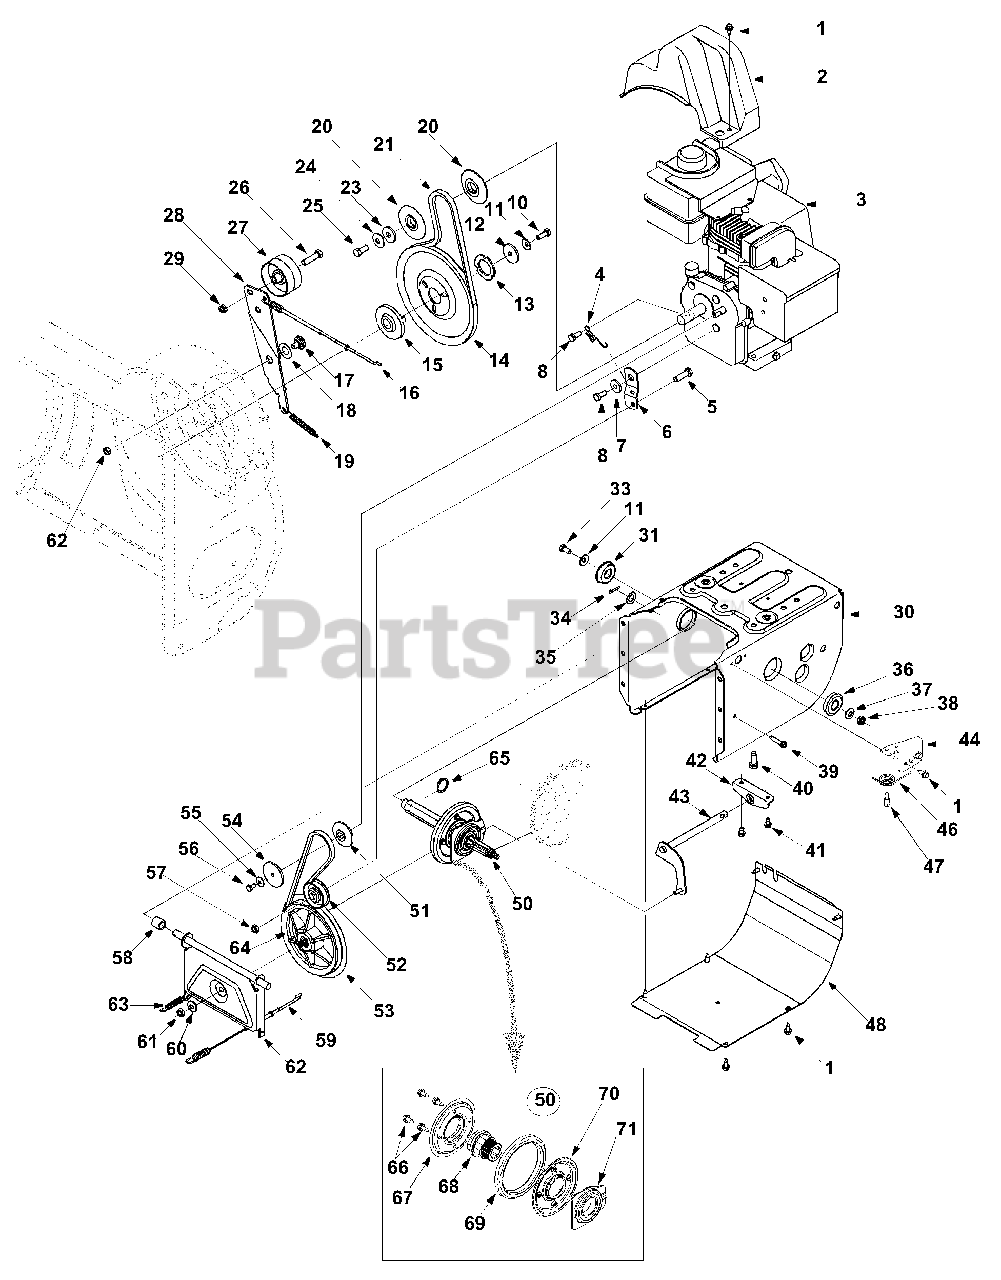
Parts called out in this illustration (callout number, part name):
1	TT Screw 1/4-20 x 0.625"
2	Belt Cover
4	Extension Spring
5	Hex Bolt 3/8-16 x 1.25"
8	Lock Bolt 5/16-24 x 0.75"
10	Lock Bolt 5/16-24 x 0.875"
11	Bell Washer
12	Flat Washer
13	Special Washer
14	Auger Pulley
15	Pulley Adapter
16	Auger Clutch Cable
17	Shoulder Screw
18	Flat Washer
19	Extension Spring
20	Pulley Half
21	V-Belt
23	Flat Washer
24	Bell Washer
25	Hex Bolt 3/8-24 x 0.875"
26	Hex Bolt (Special) 3/8-24 x 1.5"
27	Flat Idler
29	Jam Lock Nut
30	Snow Thrower Frame
31	Ball Bearing
33	Lock Bolt 5/16-18 x 0.625"
34	Cotter Pin
35	Flat Washer
36	Ball Bearing
37	Bell Washer
38	Jam Lock Nut 3/8-24
39	TT Screw 1/4-20 x 1.25"
40	Tt Sems Screw 3/8-16 x 1.0"
41	TT Screw 1/4-20 x 0.5"
43	Shift Rod Assembly
47	C Screw 1/4-28 x 0.375"
51	Pulley Half
52	Flat Idler Pulley
54	Pulley Half
55	Bell Washer
56	Hex Bolt 1/4-28 x 0.50"
57	Jam Nut 3/8-16
58	Spacer
59	Drive Cable
60	Bell Washer
61	Jam Nut
64	Friction Wheel Disc
65	Snap Ring
66	Hex washer Screw 1/4-20
67	Friction Plate
68	Friction Wheel Hub
69	Friction Wheel Rubber
70	Friction Plate
71	Friction Wheel Bearing
